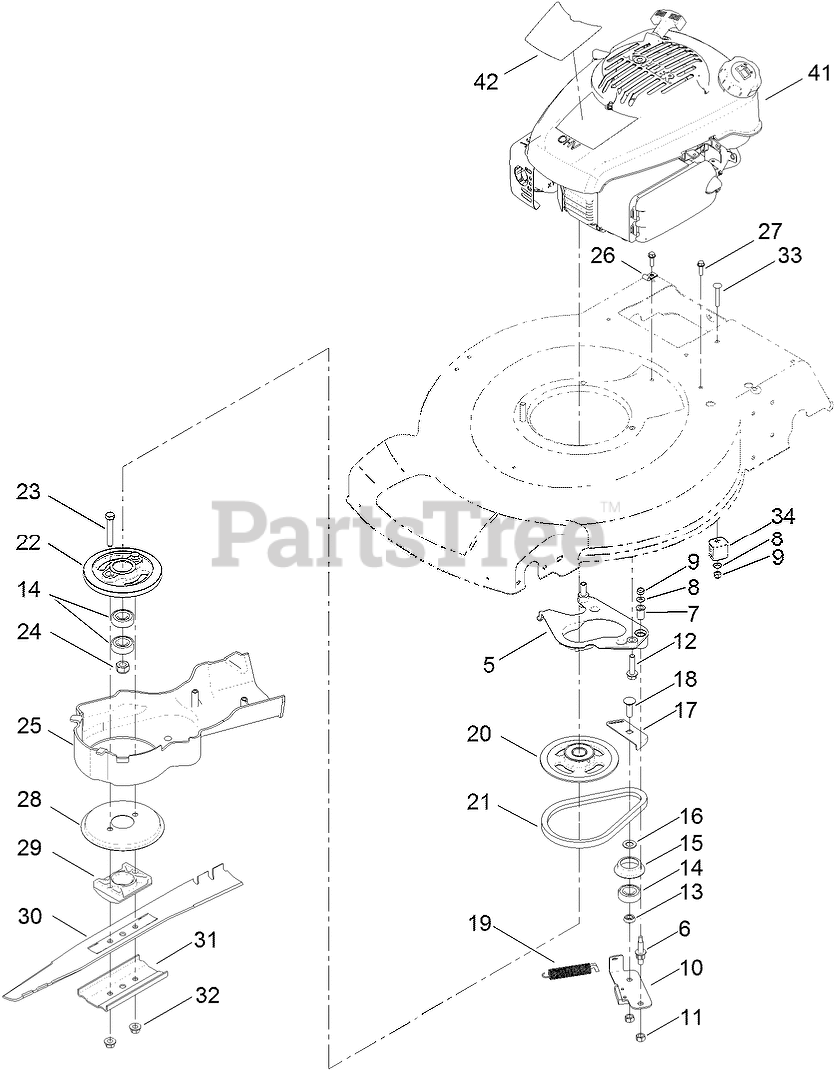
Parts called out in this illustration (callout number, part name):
5	PLATE-ANCHOR
6	BOLT-SHOULDER
7	BUSHING
8	WASHER-FLAT
9	NUT-LOCK, NI
10	BRAKE ARM ASM
12	SCREW-HWH
13	SPACER-BEARING
14	BEARING-BALL
15	RETAINER-BELT
16	WASHER-PLAIN
17	PLATE-GUIDE
18	BOLT-CARR
19	SPRING-TENSION, BRAKE
20	PULLEY
21	BELT
22	DRUM
23	SCREW-HH
24	NUT-HEX
26	CLIP-CLOSED, INSULATED
27	SCREW-HWH
28	DISC
29	SUPPORT-BLADE
30	BLADE-22 INCH
31	SUPPORT-BLADE
32	NUT-LOCK
33	SCREW-CARR
34	ANCHOR-CABLE
42	DECAL-ENGINE
